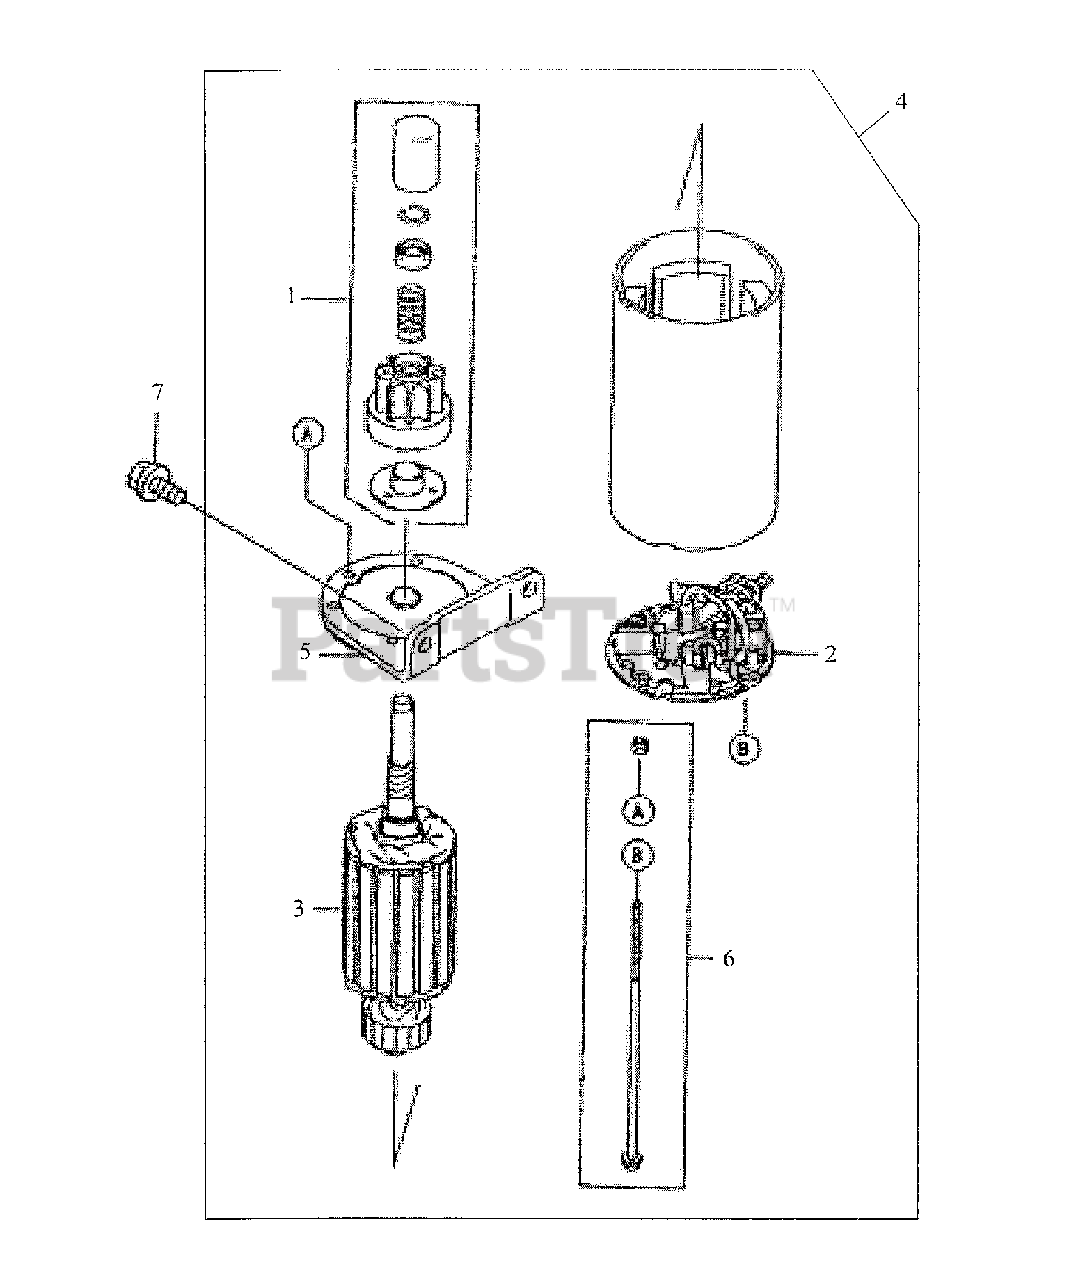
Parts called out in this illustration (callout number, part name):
1	Gear Assembly
2	Brush
4	Starter-Electric
5	Bracket-Assembly
7	Bolt-Flange
